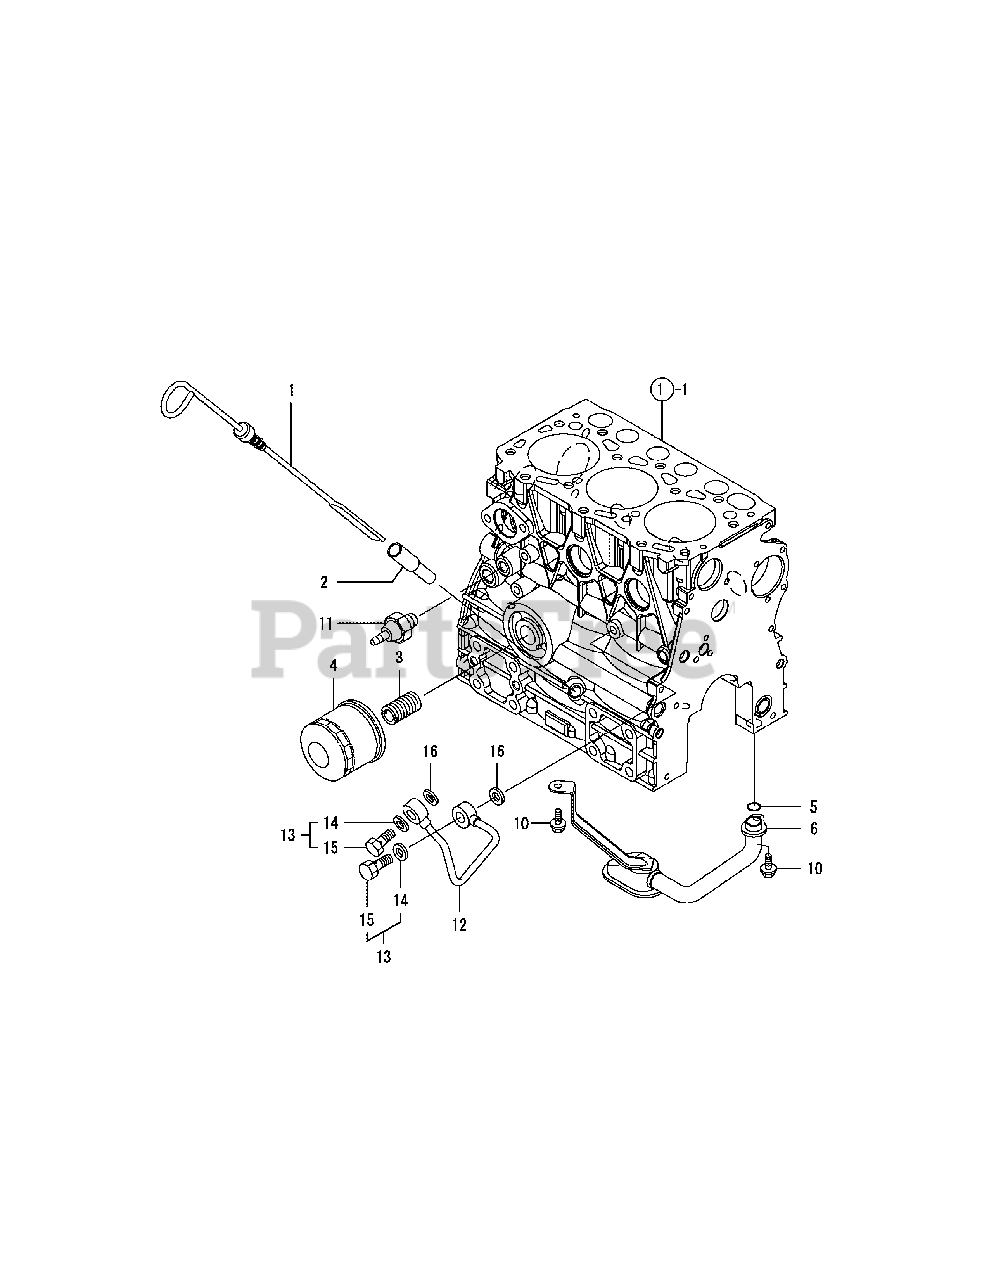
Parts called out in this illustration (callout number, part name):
1	Dipstick, Lub. Oil
2	Guide, Dipstick
4	Filter Assembly, Lub. Oil
6	Pipe Assembly, Lub. Oil
10	Bolt, 6 x 10 Plated
12	Pipe Assembly, Hydraulic
13	Bolt Assembly, Joint
